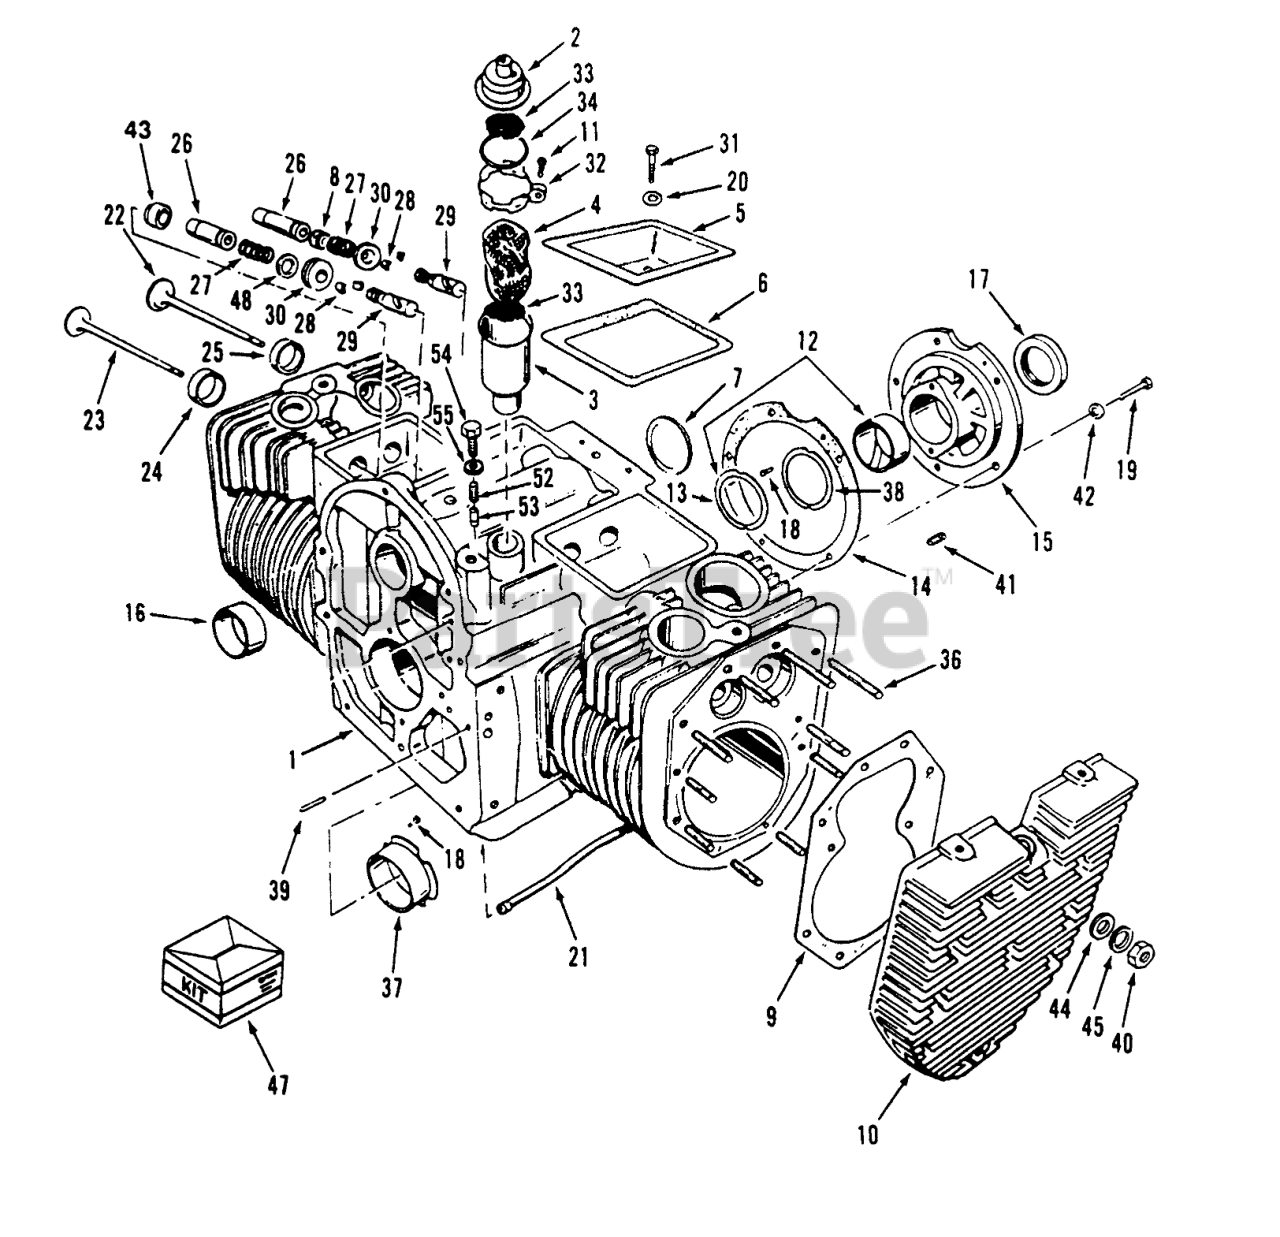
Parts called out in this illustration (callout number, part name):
1	Block-Short 24 HP. Spec E (Incl. Ref.# 3,7,13-16,18,21,24-26,30,36,38,& 39)
2	BREATHER-CAP AND VALVE
3	TUBE-BREATHER
4	FILTER
5	VALVE COMPARTMENT
6	GASKET-VALVE COVER
8	SEAL-INTAKE VALVE
9	GASKET-CYLINDER HEAD
10	HEAD-CYLINDER
11	SCREW-TAPPING, ROUND HEAD
12	BEARING KIT (STANDARD SLEEVE)
13	WASHER
14	GASKET
15	PLATE-BEARING, REAR
16	SLEEVE-BEARING
18	PIN-DRIVE
19	HEX HD CAPSCREW
20	WASHER
21	TUBE-OIL, CRANKCASE
22	Intake Valve
23	Exhaust Valve
24	INSERT
25	INSERT-VALVE SEAT
26	GUIDE-VALVE, EXHAUST
27	SPRING
28	LOCK-VALVE SPRING
29	TAPPET
30	ROTOCAP
31	SCREW - CAP HEX HEAD
32	Clamp
33	SCREEN-BREATHER TUBE
34	SEAL - O-RING
36	STUD-CYLINDER HEAD
37	KIT-BEARING, SLEEVE
39	PIN-GEAR COVER
40	NUT-HEX
41	SCREW-SET
42	WASHER-FLAT
43	Cap-Exhaust Valve
44	WASHER-FLAT HD, TREATED
45	WASHER-LOCK, COMPRESS
47	KIT-GASKET CARB REM
48	WASHER
